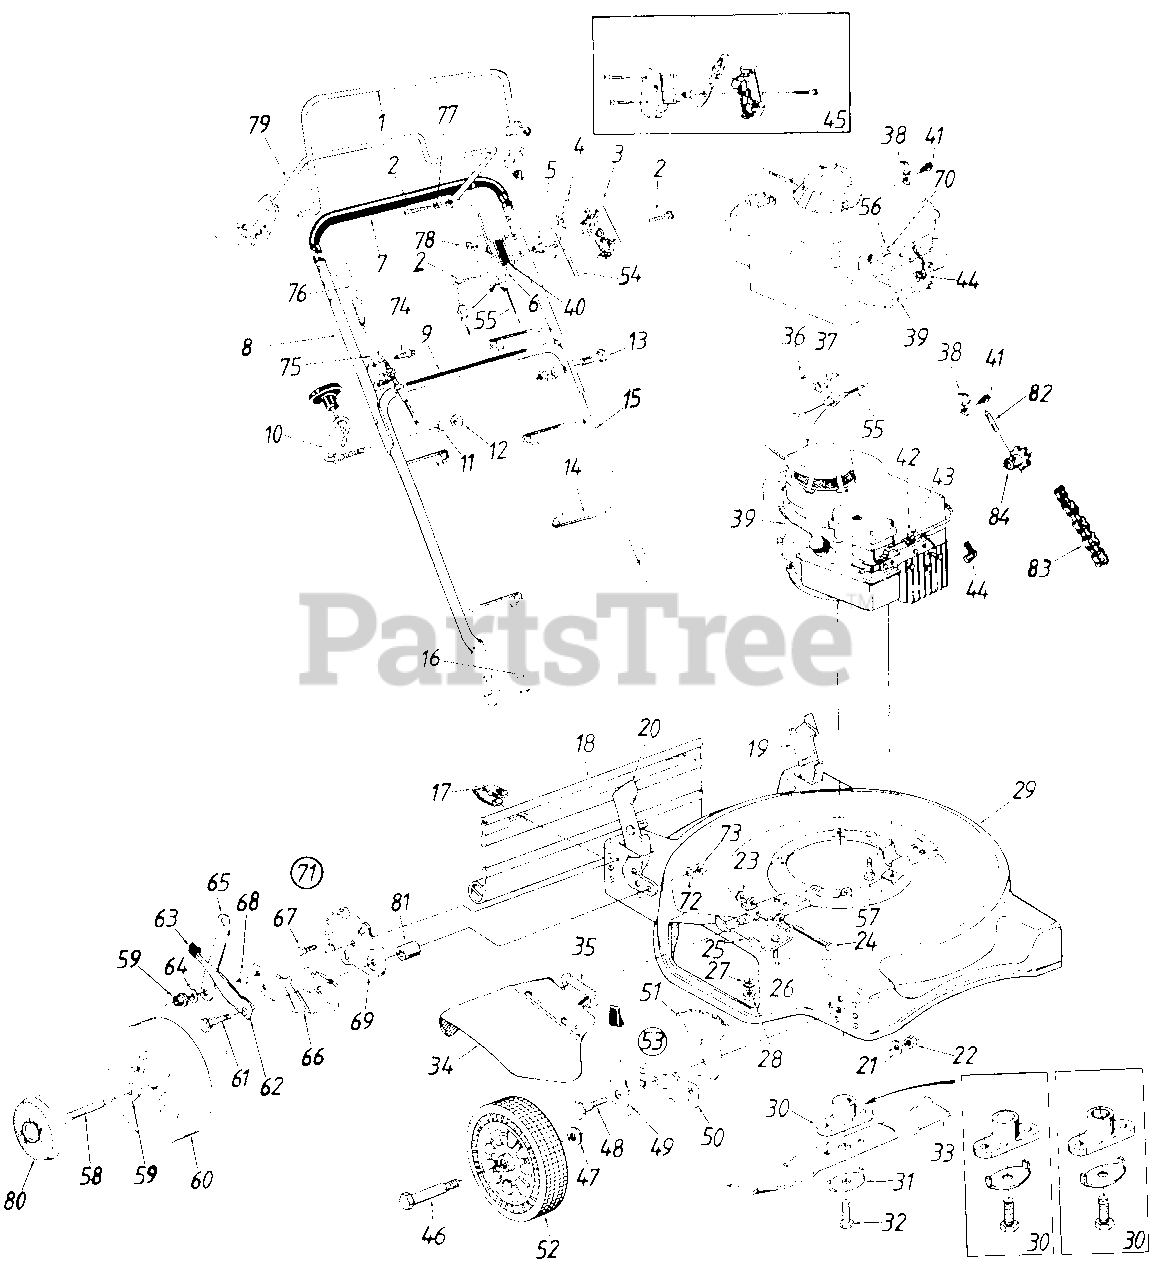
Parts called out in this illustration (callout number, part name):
1	Control Handle Ass'y.
2	Truss Mach. Scr. #12 x 1.5"
3	Control Panel Half
4	Throttle Control Lever
5	Control Disc Pin
6	Clutch Panel Half
8	Upper Handle
9	Instruction Label-Handle
10	Rope Guide Bolt
11	L-Wash. 5/16" I.D.
12	Hex Nut 5/16-18 Thd.
13	Curved Carriage Bolt 5/16-18 x 1.38" Lg.
14	Cable Tie
15	Lower Handle
16	Hairpin Cotter
17	Hinge Clip
18	Rear Flap
19	Handle Bracket Ass'y.-L.H.
20	Handle Bracket Ass'y.-R.H.
21	Bell-Wash. .39" I.D. x 1.38" O.D.
22	Hex Nut 3/8-16 Thd.
23	Push Cap 1/4" Rod
24	Pivot Pin
25	Adapter Plate
26	Hex Bolt 1/4-20 x .50" Lg.
27	L-Wash. 1/4" I.D.
28	Hex Nut 1/4-20 Thd.
29	22" Deck Ass'y.
30	Blade Adapter Kit
31	Blade Bell-Wash. .45" I.D. x 2.38"
32	Hex Bolt 3/8-24 x 1.5" L.
33	22" Blade
34	Chute Deflector Ass'y.
35	Torsion Spring
36	Pop Rivet
37	Cable Bracket
38	Cable Clamp
39	Engine
40	Control Label-Throttle
41	Hex B-Tap Scr. #10 x .38"
42	Cable Clamn
43	Hex AB-Tap Scr. #8 x 38" Lg.
44	Spark Plug Boot
45	Kit-Control Housing Comp.
46	Front Axle Bolt
47	Bell-Wash. .400" I.D. x .88"
48	Shld. Bolt .50" Dia. x .357"
49	Spring Lever Ass'y. w/Knob
50	Pivot Bar
51	Height Adj. Plate
52	Wheel Ass'y. Comp.
53	Height Adj. Ass'y. Comp.-R. H.
54	Throttle Wire-53"
55	Control Cable-39"
56	Cable Clamp
57	Hex L-Wash. HD. Scr. 3/8-16 x 1.0" Lg.
58	Rear Axle Bolt
59	Fl. Ball Brg. 1/2" I.D.
60	Rear Wheel Ass'y. Comp.
61	Shld. Bolt .50" Dia. x .433
62	Spring Lever
63	Spring Lever Knob
64	Fl-Wash. .531" I.D. x .93"
65	Link 4.58" Lg.
66	Pivot Bar R.H.
67	Hex AB-Tap 1/4-.62" Lg.
68	Bell-Wash. .380" I.D. x .88"
69	Index Plate
70	Hex B-Tap Scr. #10 x .62"
71	Rear Height Adj. Ass'y.-R.H.
72	Bell-Wash. 5/16" I.D.
73	Hex L-Nut 5/16-18 Thd.
74	Hex Wash. AB-Tap Scr. 5/16 x.75" Lg.
75	Cable Brkt.
76	Clutch Cable w/Spring-32"
77	Spacer .23" I.D. x .30" O.D.
78	Spr.-Wash. .206" I.D. x .448
79	S.P. Bail Ass'y.
80	Hub Cap
81	Spacer .383" I.D. x .503"
82	Spring Pin Spir. l" Lg.
83	#48 Chain 1/2 Pitch x 50 Links
84	10 Tooth Sprocket Ass'y.
